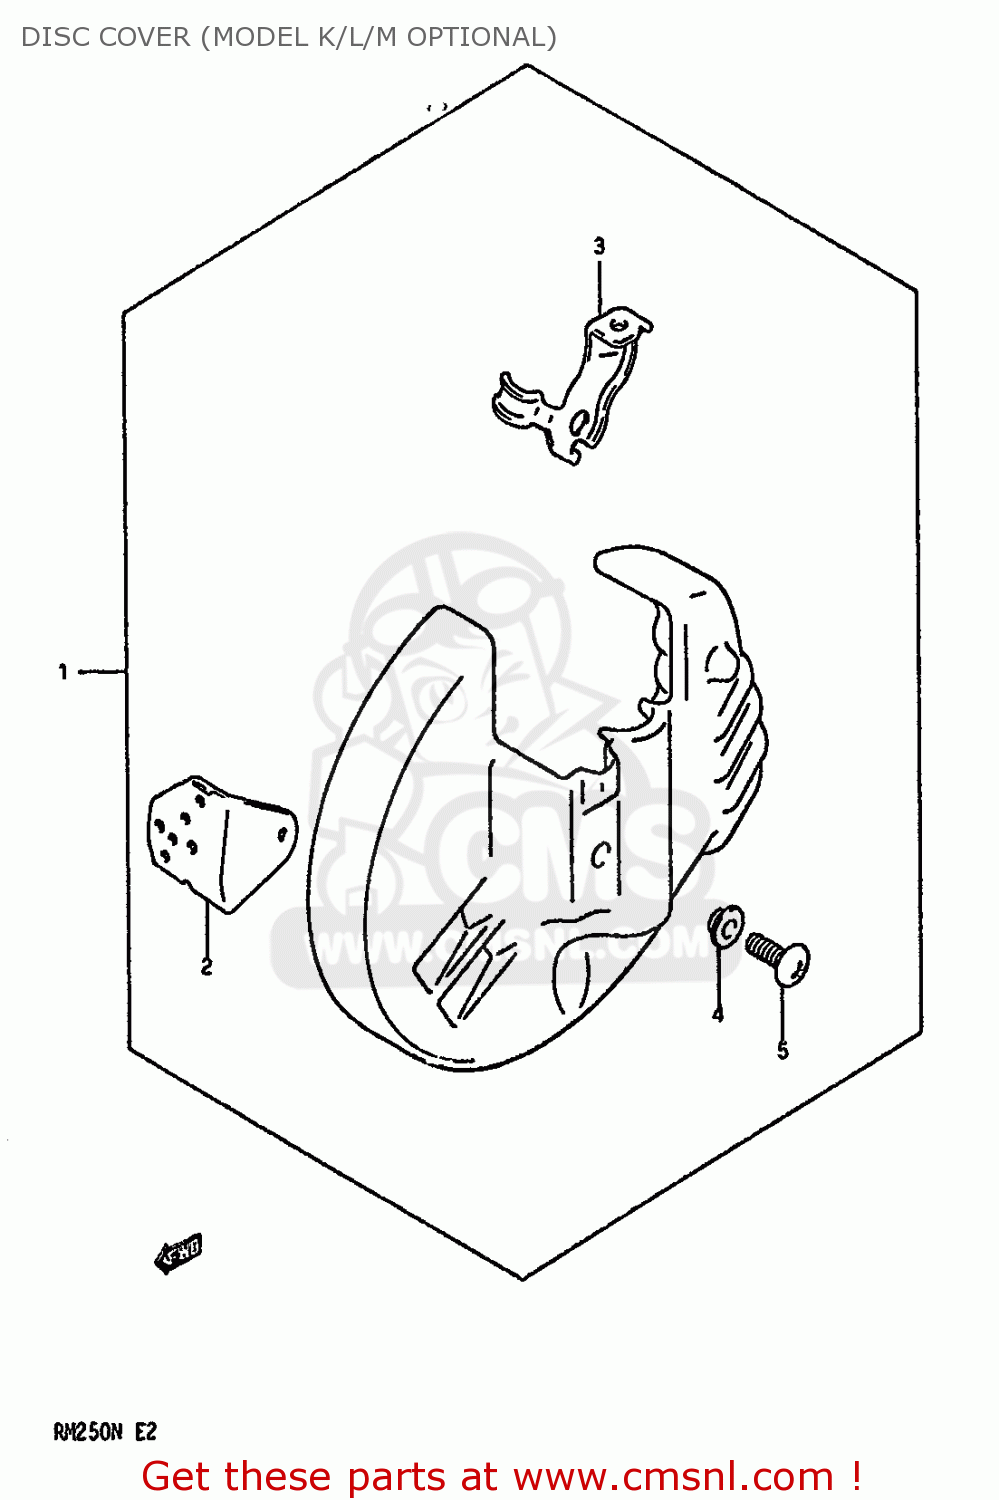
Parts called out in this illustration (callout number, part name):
1	COVER SET,FRONT DISC
2	CLAMP,HOSE
3	CLAMP,HOSE
4	WASHER
5	SCREW 6X12
